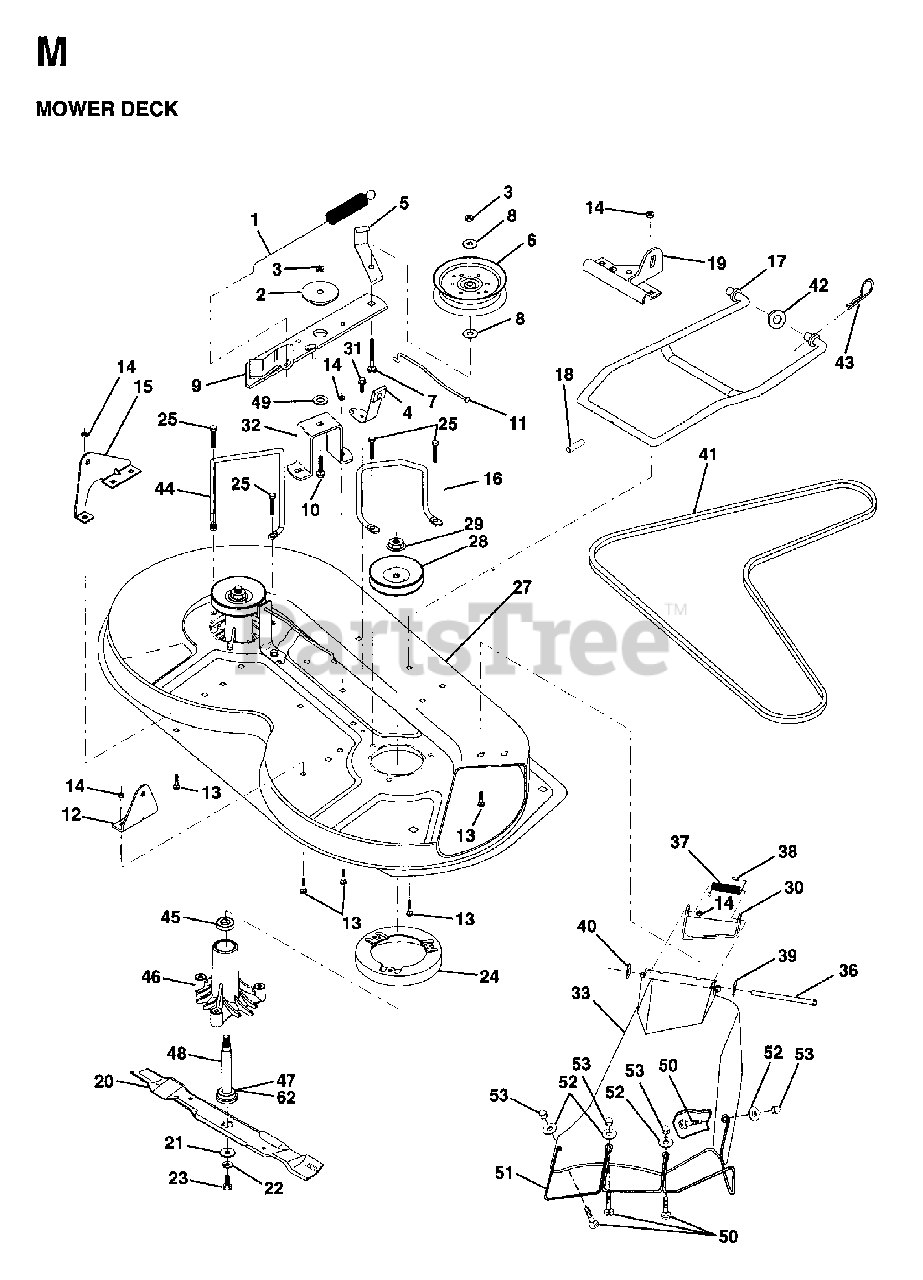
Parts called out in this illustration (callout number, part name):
1	SPRING-MOWER CLUTCH
2	SPACER RETAINER
3	LOCKNUT
4	BRAKE ASSEMBLY
5	IDLER BELT GUIDE
6	PULLEY IDLER
7	BOLT
8	WASHER
9	IDLER ARM ASSY
10	BOLT.3/8-14X1.25
11	BRAKE ROD
12	BRKT LIFT REAR
13	BOLT
14	LOCKNUT
15	BRKT LIFT REAR LH
16	BELT KEEPER
17	MOWER LINK STABILIZER
18	PIN GROOVE
19	BRKT LINK STABILIIZER
21	WASHER.BLADE
22	LOCKWASHER
23	BLADE BOLT
24	STRIPPER
25	SCREW
27	MOWER HOUSING
28	PULLEY, MANDREL
29	NUT
30	BRACKET ASM DEFLECTOR
32	SUPT,IDLER ARM
33	DEFLECTOR
36	HINGE ROD
37	SPRING TORSION
38	CAP-SLEEVE LT
39	WASHER
40	NUT PUSH M
42	WASHER
43	SPRING RETAINER
44	KEEPER LH
46	HSG MANDREL
47	BEARING
48	SHAFT ASM VENT
49	HARDENED WASHER
50	SCREW
53	NUT
62	WASHER FELT
